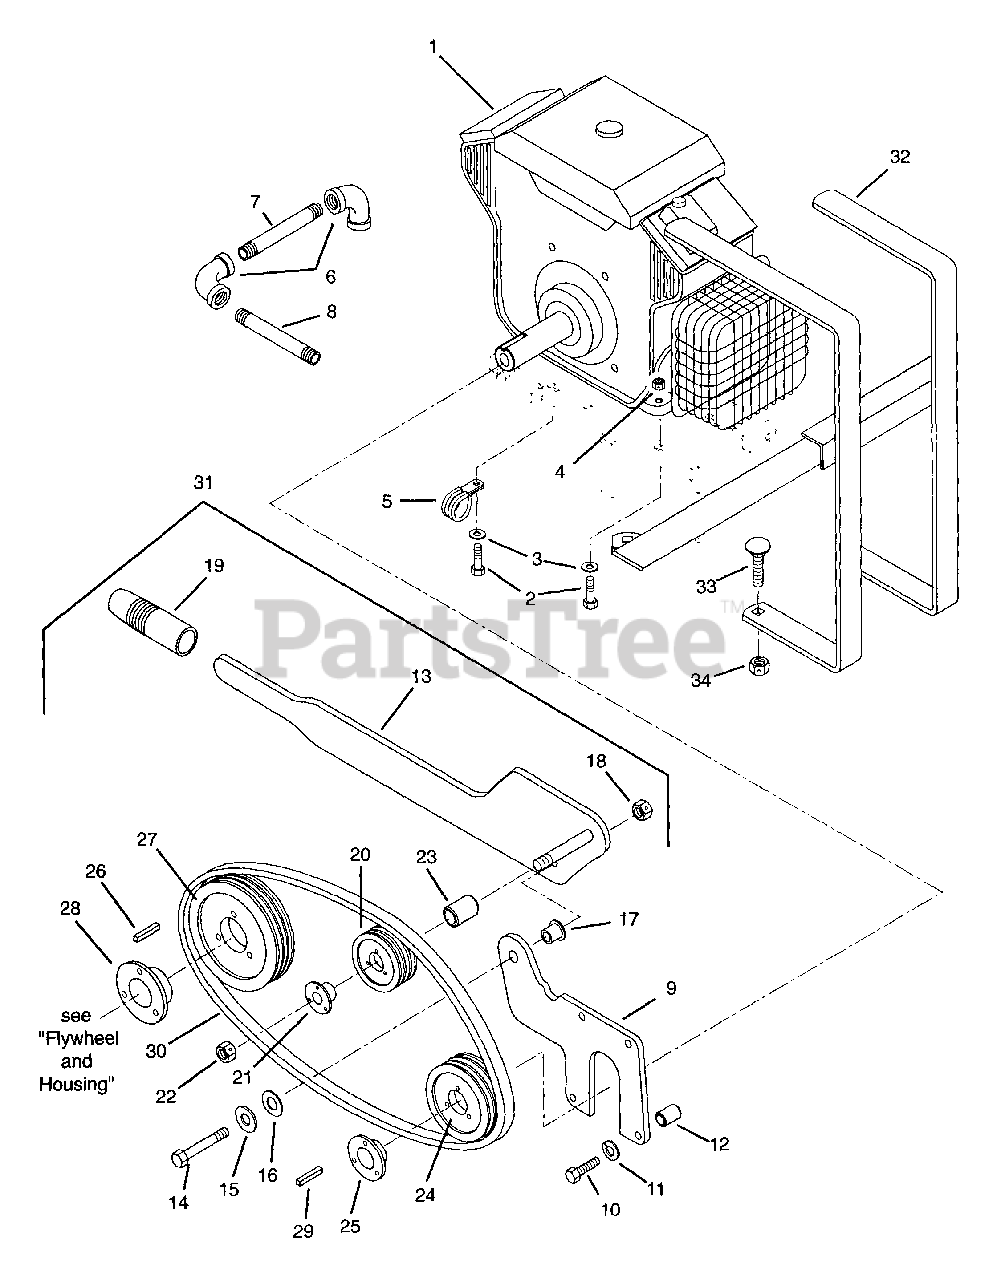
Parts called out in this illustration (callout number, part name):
1	Engine Kohler 18 HP Spec. # PS62556
2	Bolt-Hex .38-16 x 1.75 Grade 5
3	Washer-Flat-Steel .438 x 1.00 x .083
4	Nut-Locking-Center .38-16
6	Elbow .375-18
7	Nipple
9	Engine Bracket Weldment
10	Bolt-Hex .44-14 x 2.25 Grade 5
11	Washer-Lock .44 x .109
12	Spacer .47 x .75 x 1.18
13	Clutch Handle Weldment
14	Bolt-Hex .50-13 x 2.00 Grade 5
15	Washer-Flat-Steel .531 x 1.062 x .095
16	Washer .50 Bronze
17	Bushing-Flange .500 x .750 x .625 x .937
18	Nut-Locking-Center .50-13
19	Grip
20	Pulley 3P 3V4.1
21	Idler with Bearings and Bolts
22	Nut-Locking-Center .62-11
23	Spacer .630 x .878 x 1.000
25	Bushing-SH 1-1/8 in.
26	Key-Straight .38 x 2.0 x .38
27	Flywheel Sheave 3-3V80
28	Bushing, Sk x 1-1/2 in.
29	Key-Square .25 x 1.25 x .25 SAE
30	V-Belt 3/3VX500
31	Idler Clutch Kit 1-1/8 in.
32	Guard-Engine Heat Weldment Assembly
33	Bolt-Round Square Neck .38-16 x 1.00 Grade 2
34	Nut-Locking-Center .38-16
